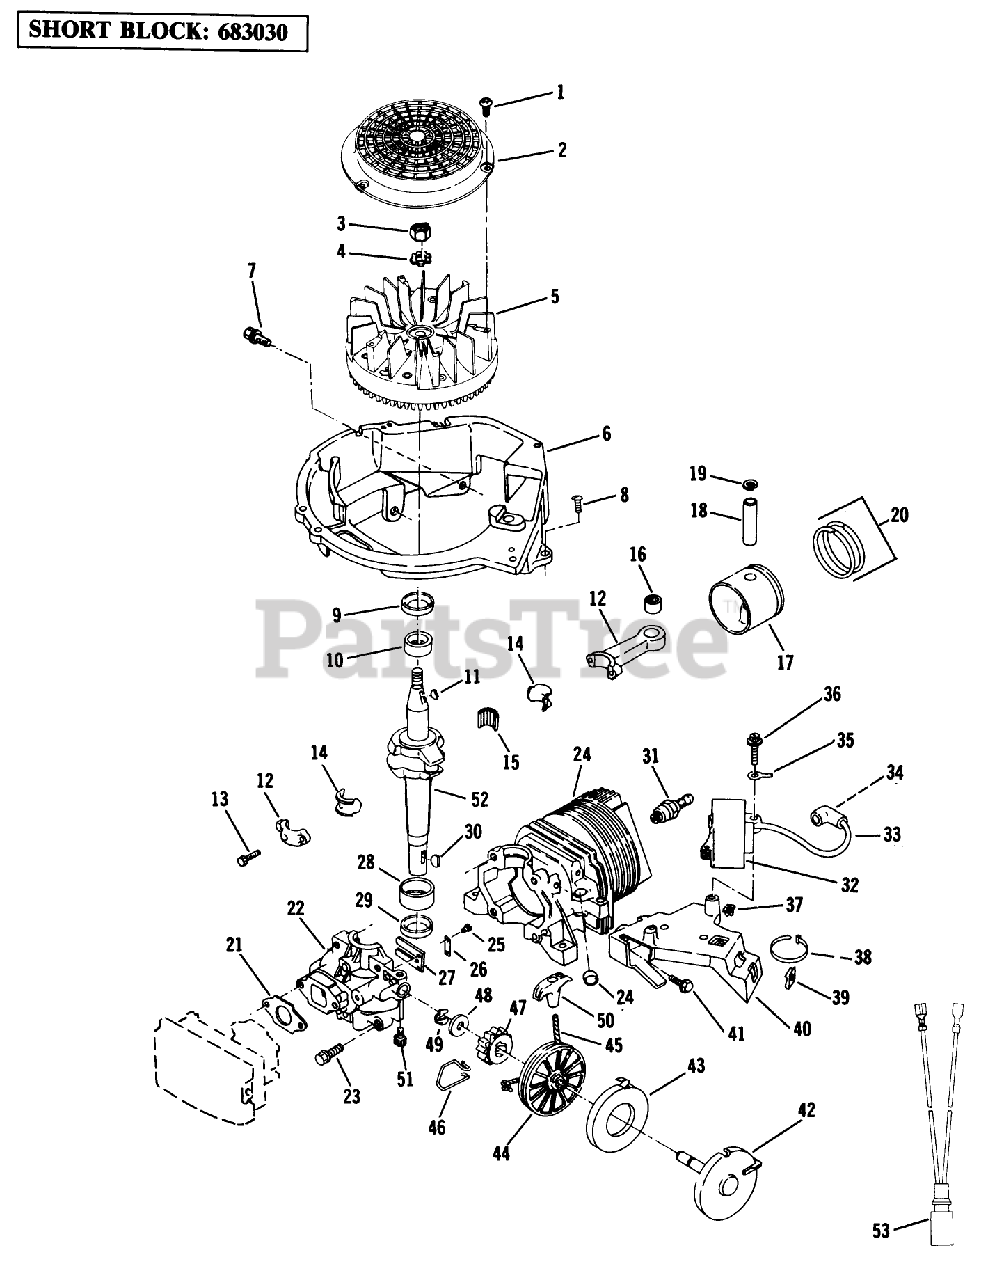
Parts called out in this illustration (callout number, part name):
1	SCREW F
2	SCREEN F'WHEEL S
3	NUT
7	SCREW-SEMS
8	SCREW F
10	BEARING V
11	KEY
13	SCREW-HSH
14	LINER ASM
16	BEARING AY F
19	RING-RETAINING
21	GASKET CARB S
23	SCREW S
24	PLUG-CORE VF
26	PLATE-BACKUP, REED
28	BEARING V
29	SEAL-OIL
33	HT LEAD&COVER XEV
35	TERMINAL S
37	NUT-CLIP
39	NUT - SPEED S
44	PULLEY STARTER S
46	SPRING F
48	WASHER S
50	HANDLE STARTER S
53	WIRE HARNESS
